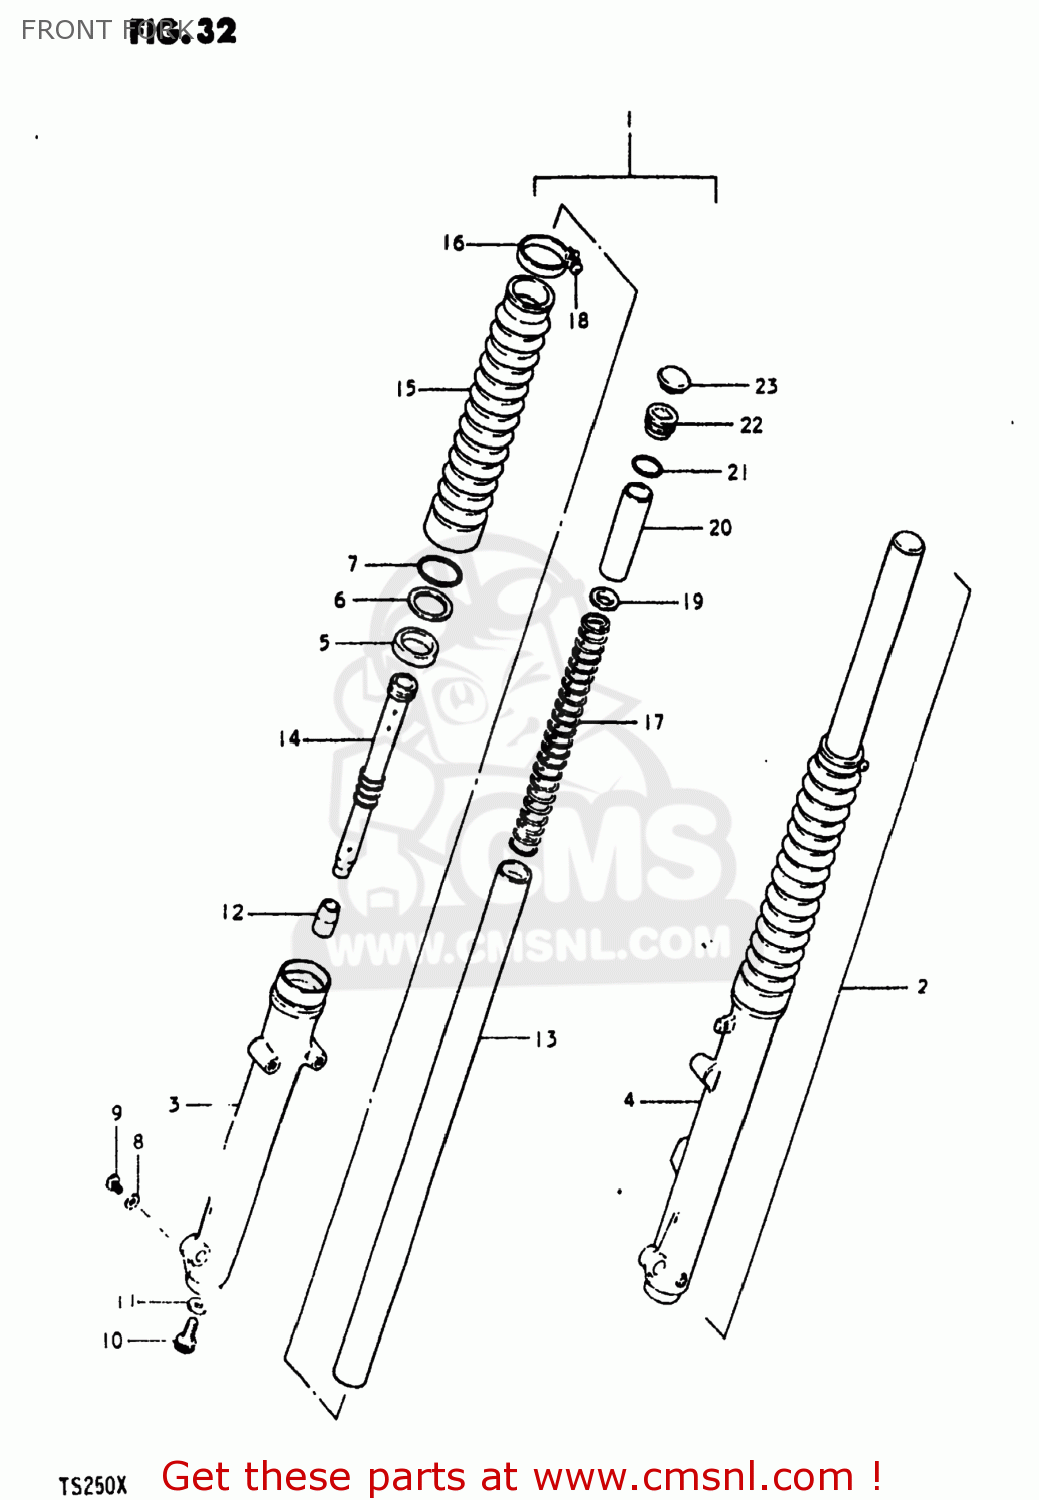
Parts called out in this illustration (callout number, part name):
1	DAMPER ASSEMBLY,FRONT FORK,RIGHT
2	DAMPER ASSEMBLY,LEFT
3	TUBE,OUTER,RIGHT
4	TUBE,FORK,LEFT,OUTER
5	OIL SEAL,FRONT FORK
6	RING,FORK BACK UP
7	CIRCLIP,FORK OIL SEAL
8	GASKET,DRAIN,PLUG (NAS)
9	SCREW
10	BOLT,FORK CYLINDER(10X25)
11	GASKET (NAS)
12	PIECE,OIL LOCK
13	TUBE,FORK,INNER
14	CYLINDER,FRONT FORK
15	BOOT,FRONT FORK COVER
16	BAND,BOOT
17	SPRING,FRONT FORK
18	SCREW
19	GUIDE,FRONT FORK SPRING C
20	SPACER,FRONT FORK SPRING
21	O RING
22	CAP,FORK INNER TUBE
23	CAP,FRONT FORK
